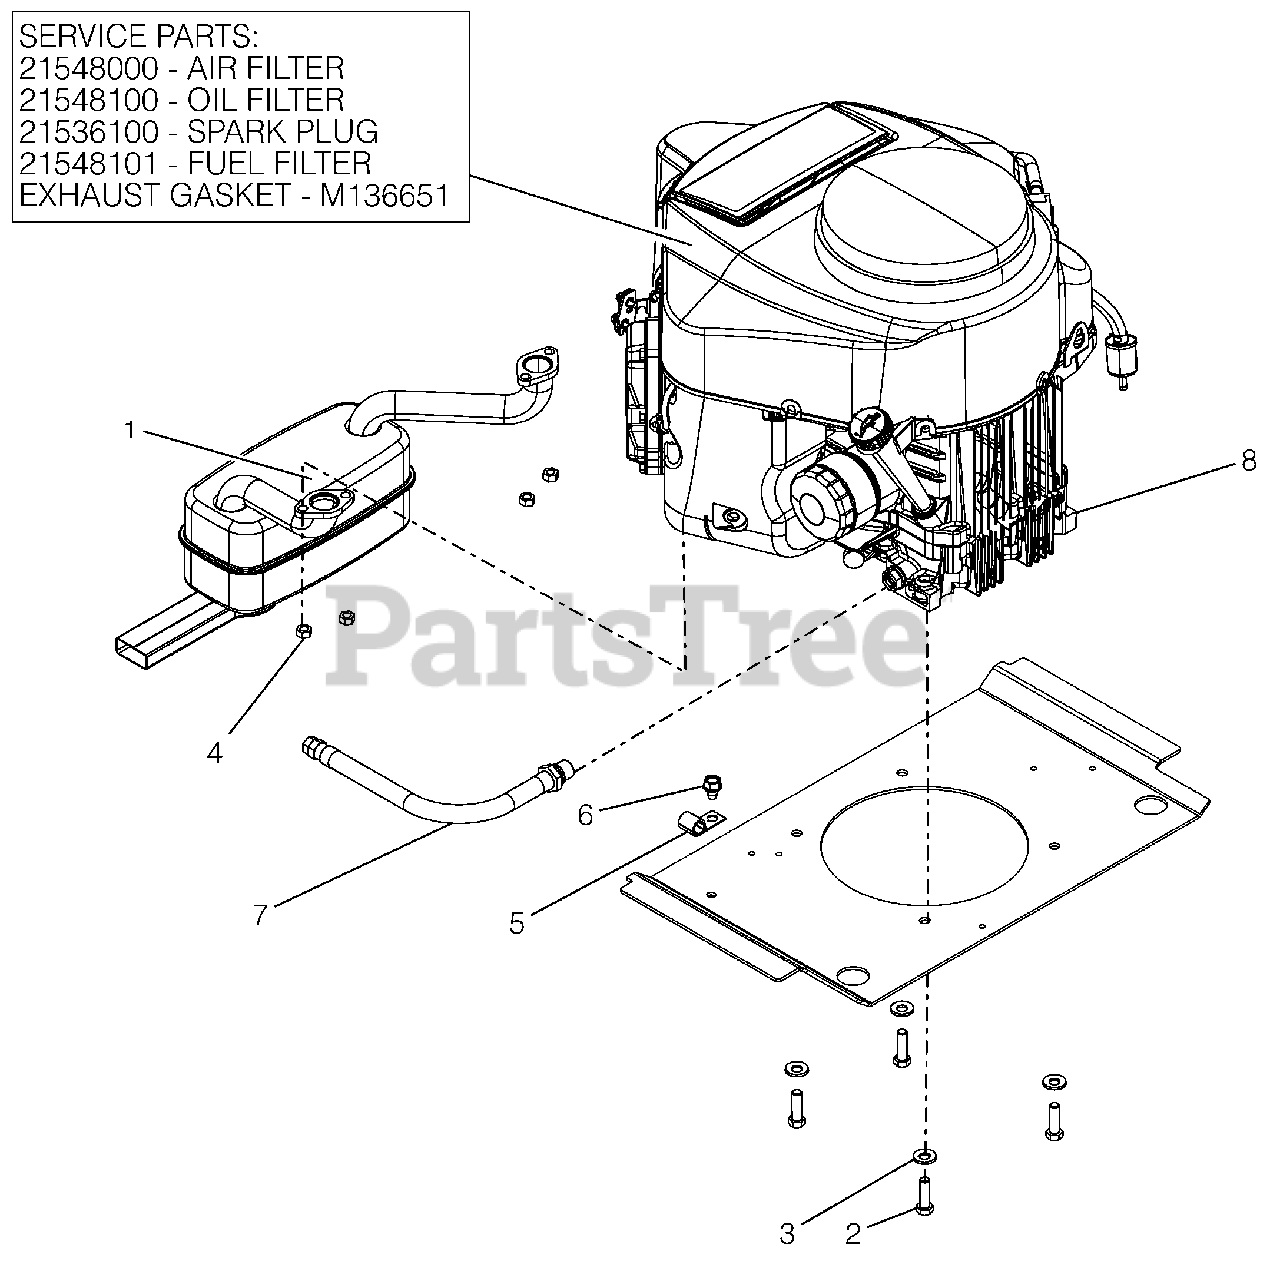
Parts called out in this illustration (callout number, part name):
1	MUFFLER, KAWASAKI
2	BLT-HEX.38-16X1.25 G5YZ NYTORQ
3	WASHER, 3/8" SPRING DISC
4	NUT-LK-TOP M8-1.25 YWZC
6	@SCR-TAP .38-16X.50 HWH TR YWZ
7	HOSE, OIL DRAIN
8	ENGINE, KAWASAKI FR730 24HP
8	AIR FILTER, KAWASAKI FR
8	OIL FILTER, KAWASAKI FR
8	PLUG, SPARK
8	FUEL FILTER-KAWASAKI FR
8	GASKET, MUFFLER #
